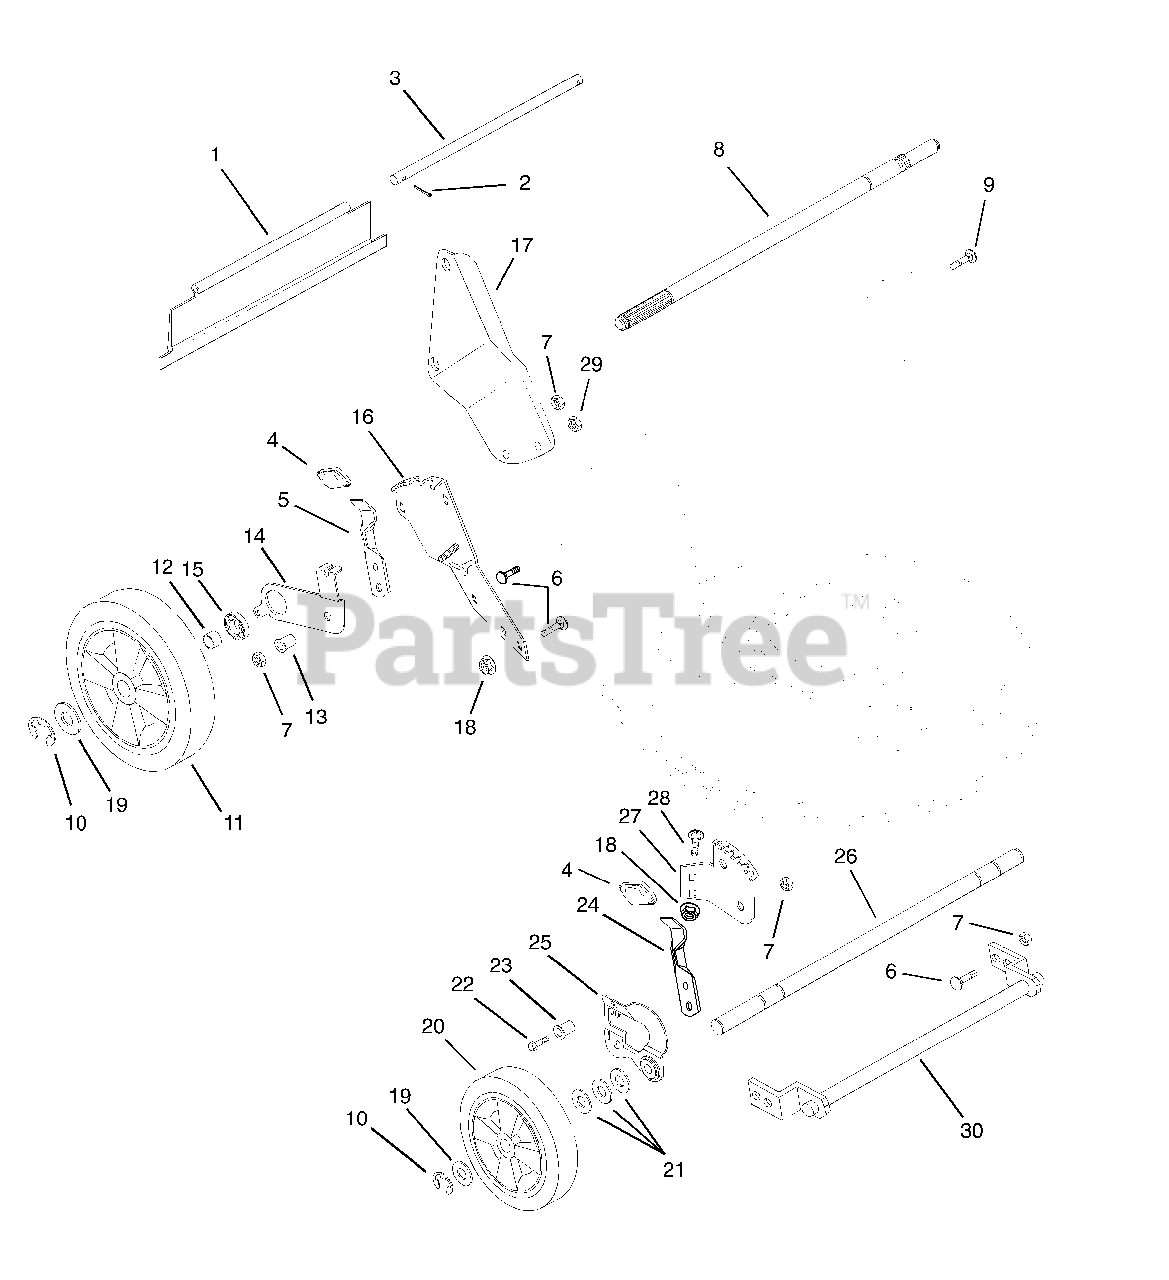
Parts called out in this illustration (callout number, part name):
1	Rear Protective Guard, Self Propelled
2	Pin-Cotter .06 x .50
3	Rod
5	Height Adjustment Lever
6	Bolt-Round Head Square Neck .31-18 x .62
7	Nut-Locking-Center .31-18
8	Rear Axle
9	Bolt-Round Head Square Neck .31-18 x 1.00
10	Ring-Retaining-External .500 x .042
11	Wheel, Left Hand-10.50"
11	Wheel, Right Hand-10.50"
11	Tire Skin 10.5 x 2.0
12	Spacer Tube, Self Propelled
13	Bushing-Flange .312 x .500 x .344 x .880
14	Right Hand Rear Adjuster Bracket
14	Left Hand Rear Adjuster Bracket
15	Bearing-Ball .625 x 1.382 x .50
16	Quadrant, Rear-Left Hand
16	Quadrant, Rear-Right Hand
17	Weldment, Right Hand Handlebar Mount
17	Weldment, Left Hand Handlebar Mount
18	Nut-Locking-Flanged .31-18
19	Washer-Flat-Steel .505 x .880 x .079
21	Washer-Flat-Steel .520 x .827 x .062
22	Bolt-Hex .31-18 x 1.00 Grade 5
23	Bushing-Flange .312 x .500 x .344 x .880
24	Lever, Front Height Adjustment
25	Right Hand Adjuster Bracket
25	Left Hand Adjuster Bracket
26	Front Axle
27	Front Quadrant, Left Hand
27	Front Quadrant, Right Hand
28	Bolt-Round Head Square Neck .31-18 x .50
29	Nut-Locking-Nylon .31-18
30	Weldment, Dethatcher Retainer
